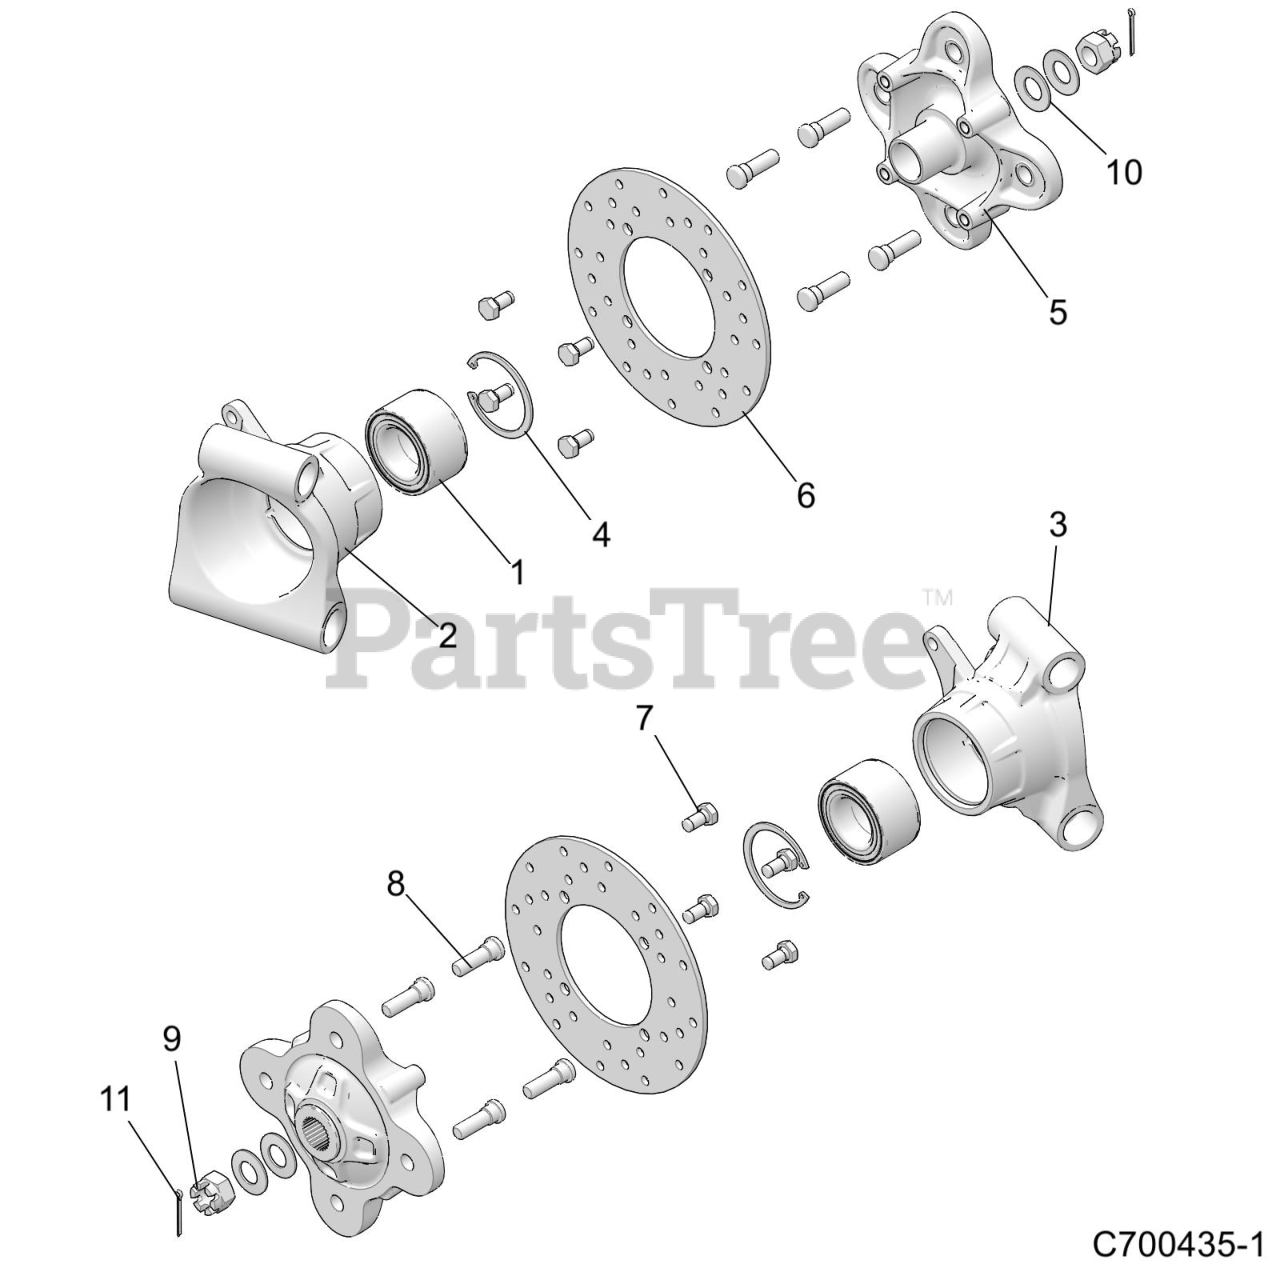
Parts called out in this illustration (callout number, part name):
1	BEARING-WHEEL,40X74X40MM
2	CARRIER-BEARING,LH
3	CARRIER-BEARING,RH
4	RING,RETAINING
5	HUB-WHEEL,MACH,BLK
6	DISC-BRAKE,REAR,8.625X.188
7	SCR-M10X1.5X20,8.8 ZY3
8	STUD-WHEEL,M12-1.5
9	NUT-M18X1.5,CASTLE,ZINC/YELLOW
10	WSHR-AXLE,M18,42X4.5
11	PIN, COTTER
